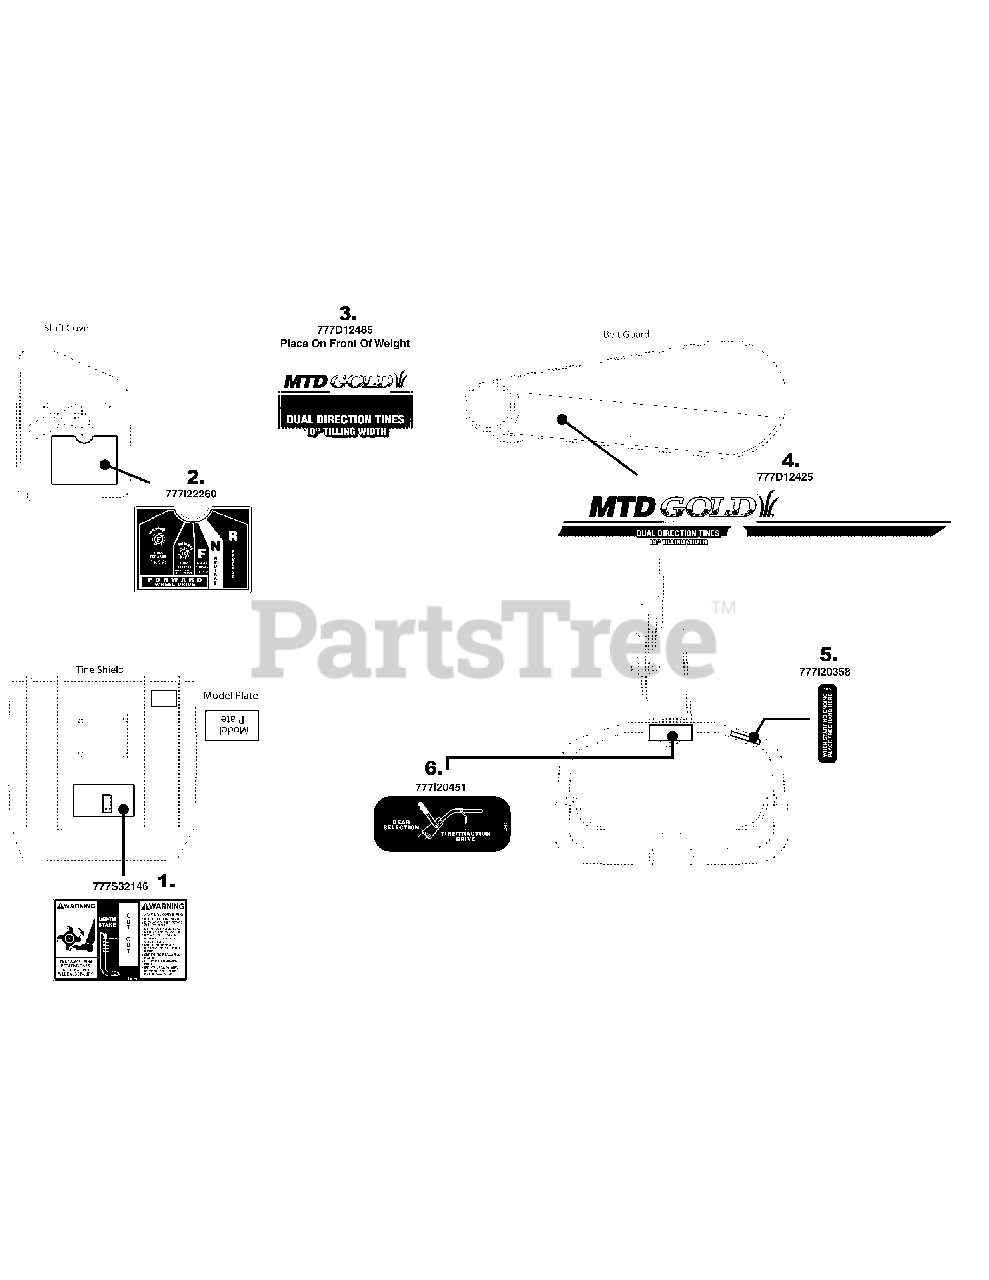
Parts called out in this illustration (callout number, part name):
1	LABEL-TINE SHIELD
2	LABEL-SHIFT P0SITION
3	LABEL-TILLER FRONT WEIGHT GOLD
4	LABEL-TILLER BELT GUARD MTD GOLD
5	LABEL-PLACE HAND HERE
6	LABEL-GEAR/TRACTIO
